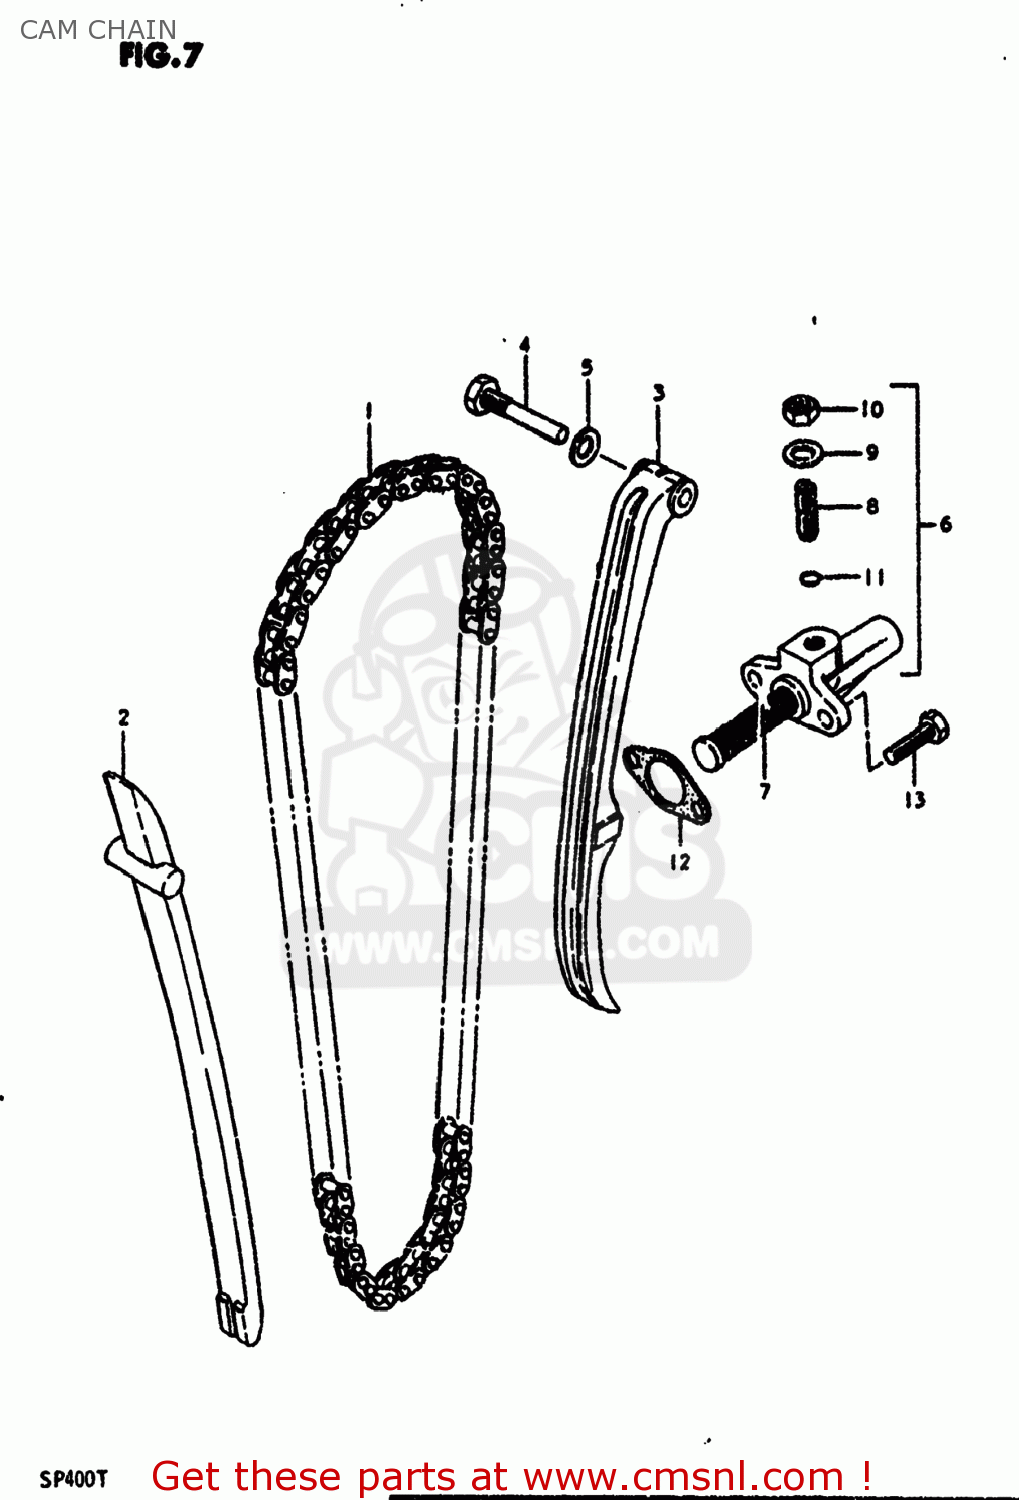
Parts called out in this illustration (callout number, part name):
1	CHAIN,CAMSHAFT DRIVE
2	GUIDE,CAM CHAIN
3	TENSIONER,CAM CHAIN
4	BOLT,CAM CHAIN TENSIONER
5	GASKET 8.2X14X1 (NAS)
6	ADJUSTER ASSEMBLY,TENSIONER
7	SPRING
8	SCREW
9	WASHER
10	NUT
11	O-RING
12	GASKET,TENSIONER ADJUSTER (NAS)
13	BOLT
